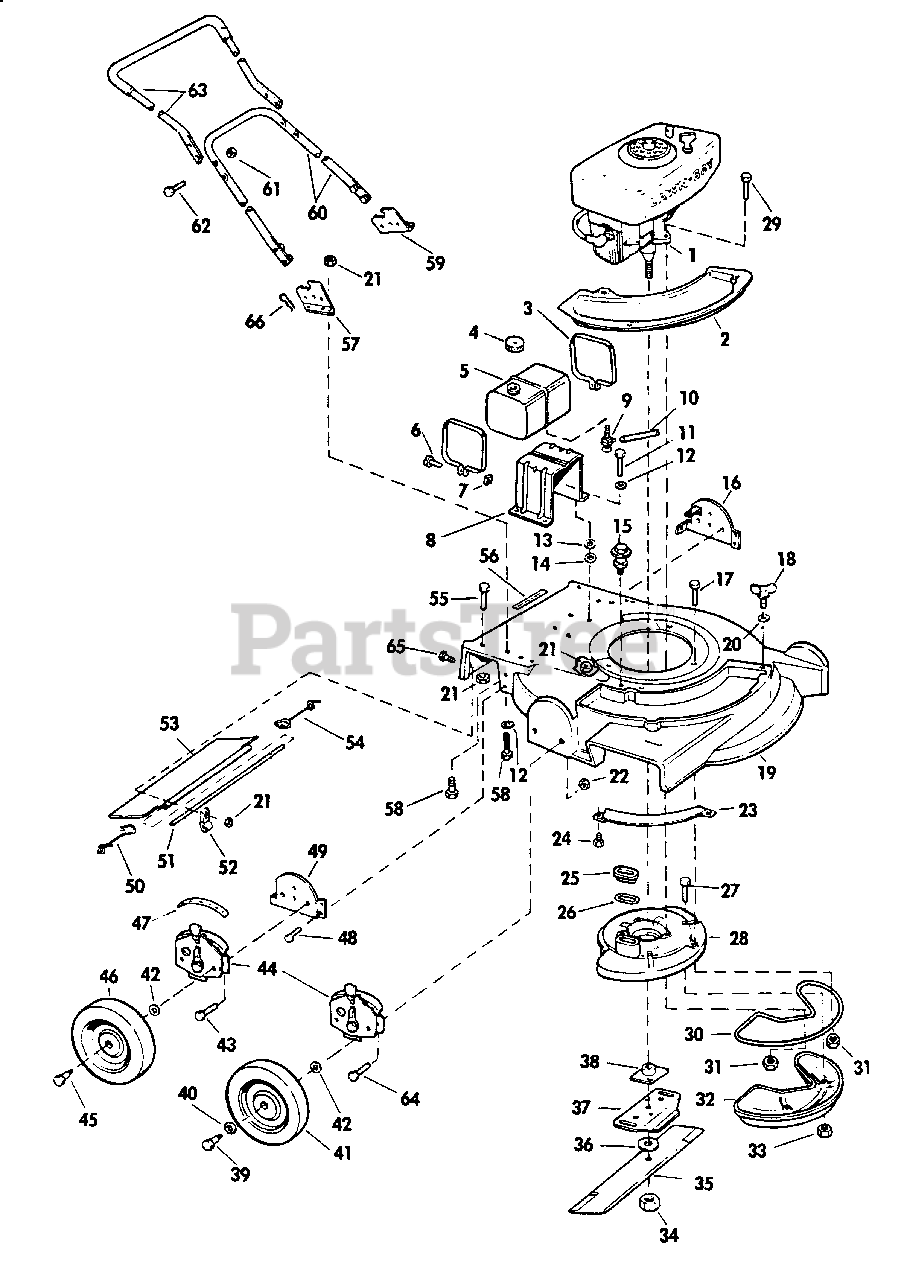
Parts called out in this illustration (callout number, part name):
1	See Note #1 at bottom of this page.
2	Cover Assembly
3	Strap
4	Gas Cap
5	Gas Tank
6	Screw
7	Nut
8	Bracket
9	Shut-Off Valve & Screen
10	Line-Gas
11	Screw
12	Washer
13	Grommet
14	Washer
15	Screw
16	Bracket-L.H.
17	Screw-Muffler Plate to Housing
18	Wing Screw
19	Housing Assembly-21"
20	Grommet
21	Nut-Nylok
22	Nut-Nylok
23	Toe Bar
24	Screw
25	Sleeve-Muffler Gasket
26	Gasket-Exhaust
27	Screw
28	Muffler Plate Assembly
29	Screw
30	Gasket-Muffler
31	Nut-Nylok
32	Muffler
33	Nut-Muffler to Muffler Plate Screw
34	Blade Nut
35	Blade-21"
36	Washer-Blade
37	Stiffener-Blade
38	Collar and Plate
39	Wheel Bolt-Shoulder
40	Washer
41	Wheel & Tire Assy.-6"
42	Washer
43	Screw-Height Adjustment to Mounting Bracket
44	Height Adjustment Assy.
45	Wheel Bolt-Shoulder
46	Wheel & Tire Assy.-8"
47	Decal
48	Screw
49	Bracket-R.H.
50	Spring-R.H.
51	Rod
52	Clamp
53	Shield
54	Spring-L.H.
55	Screw
56	21" Heavy Duty Decal
57	Handle Bracket, Right
58	Screw
59	Handle Bracket, left
60	Handle Bottom and Pin Assembly
61	Nut-Handle
62	Screw-Handle
63	Top Handle Sect. and Grip Assembly
64	Screw-Height Adj. to Housing Assy.
65	Screw
66	Hair Pin Handle
